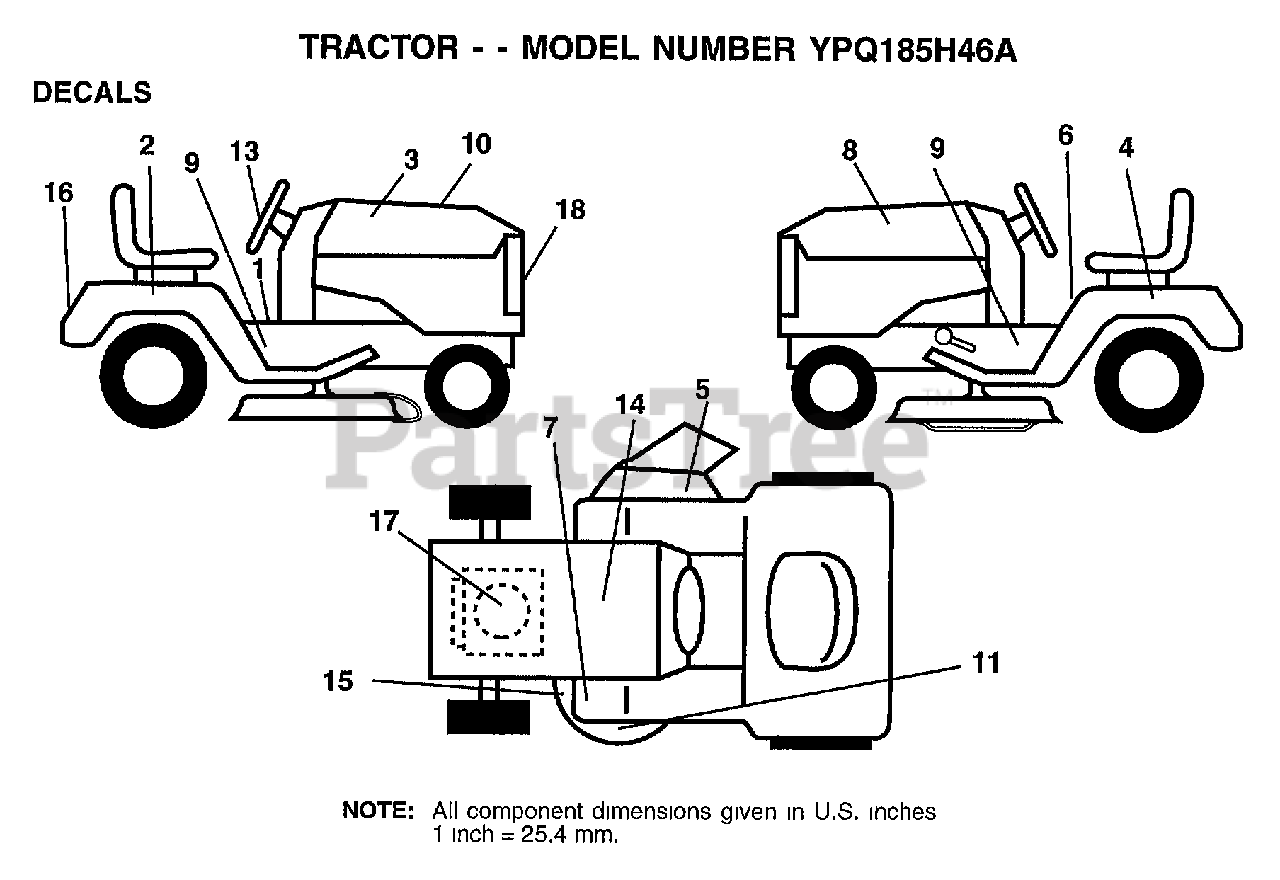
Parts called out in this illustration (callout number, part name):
1	DECAL SADDLE OPER
1	VALVE CAP
2	DECAL FENDER RH
2	VALVE STEM LT
3	DECAL HOOD RH18.5
4	DECAL FENDER LH
4	TUBE.5.3/4.5/6
5	"DECAL, WARNING"
5	"RIM ASM 6"" FRT"
6	DECAL.CAUT.ENG/FR
6	FITTING LT
7	DECAL T
7	"FLANGE, BEARING"
8	DECAL HOOD LH18.6
8	"RIM AS 8"" REAR"
9	"DECAL-CHASSIS,46"""
10	DECAL, HOOD REPLACE PARTS
10	TUBE.18X9.5-8
11	DECAL.MOWER
11	HUB CAP
13	DECAL INS STRG WH
14	DECAL.BATRY.3-3908
15	"DECAL.V.BELT.44"""
16	DECAL FENDER
17	DECAL.HP.ENGINE
